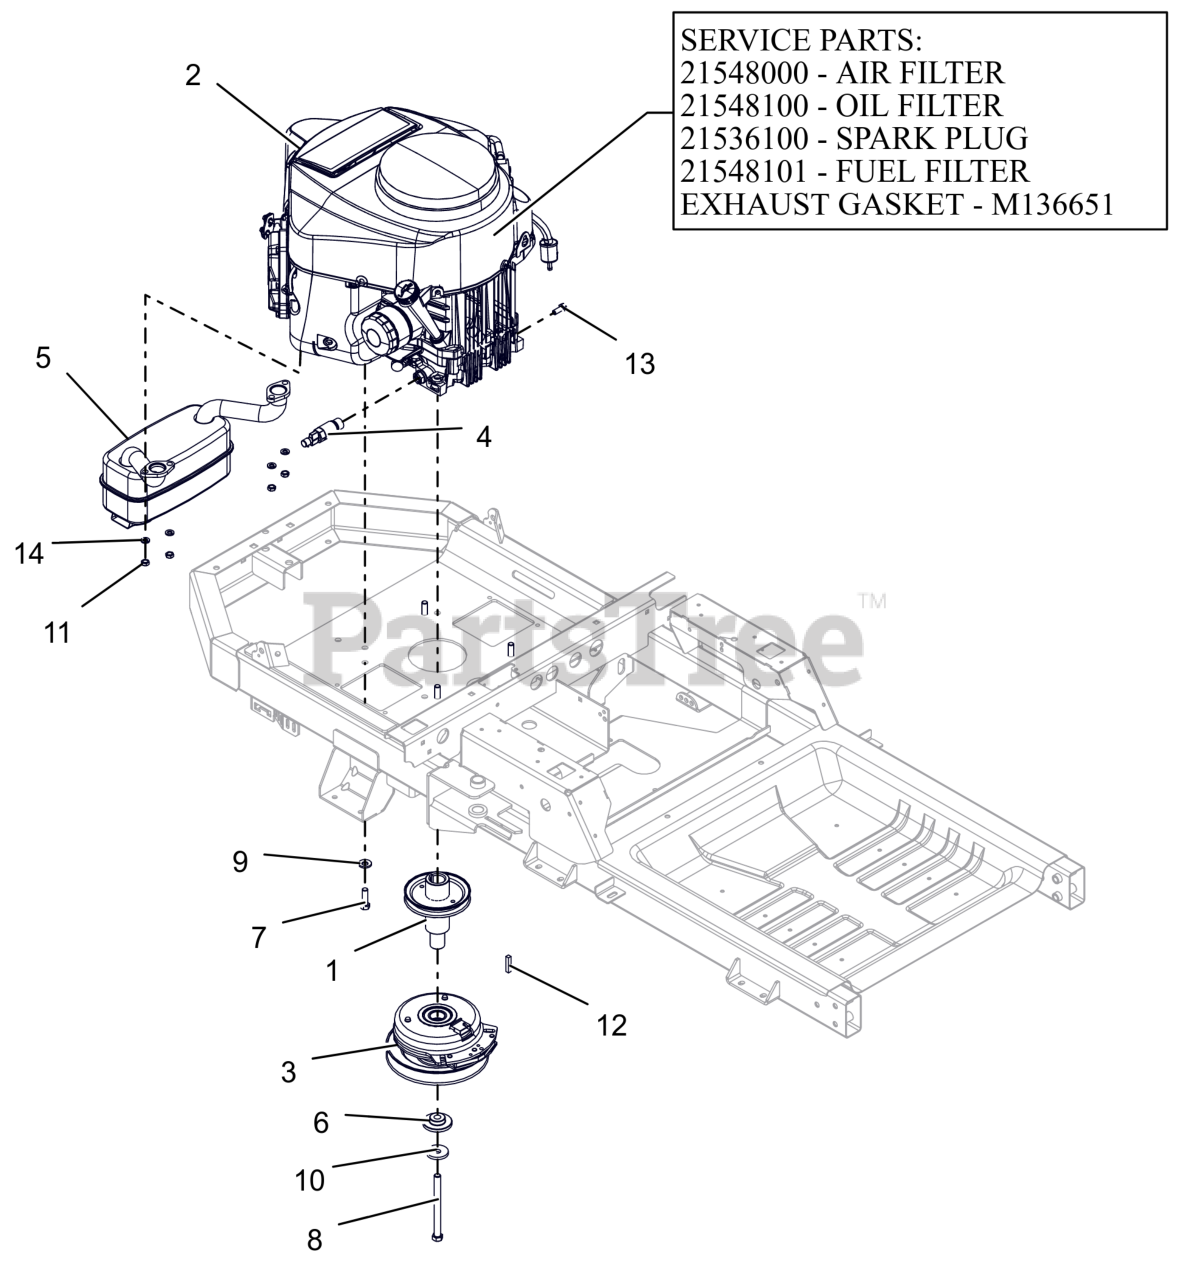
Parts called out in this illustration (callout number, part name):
1	WLDMT, DRIVE SHEAVE (LG XL)CZC
2	ENGINE, KAWASAKI FR730 24HP
2	AIR FILTER, KAWASAKI FR
2	OIL FILTER, KAWASAKI FR
2	PLUG, SPARK
2	FUEL FILTER-KAWASAKI FR
2	GASKET, MUFFLER #
3	CLUTCH,105FTLB MONOPOLE 6.83"
4	DRAIN, OIL M20X2.5
5	MUFFLER - KAWASAKI
6	BSHG-FLG .469X1.06X.574X2.0
7	BLT, HEX .38-16X1.25 G5 ZCC NT
8	BLT-HEX.438-20X5 GR8 YZ NYTORQ
9	WASHER, 3/8" SPRING DISC
10	WASHER, 7/16" SPRING DISK
11	NUT, LK-CTR-JAM M8-1.25 GR8.8 ZC120
12	KEY-SQ .25 X 1.25 X .25 SAE
13	BLT, HEX M8-1.25X20 G8.8 ZCC
14	WSHR,LK-REG .312X.078 ZCC
